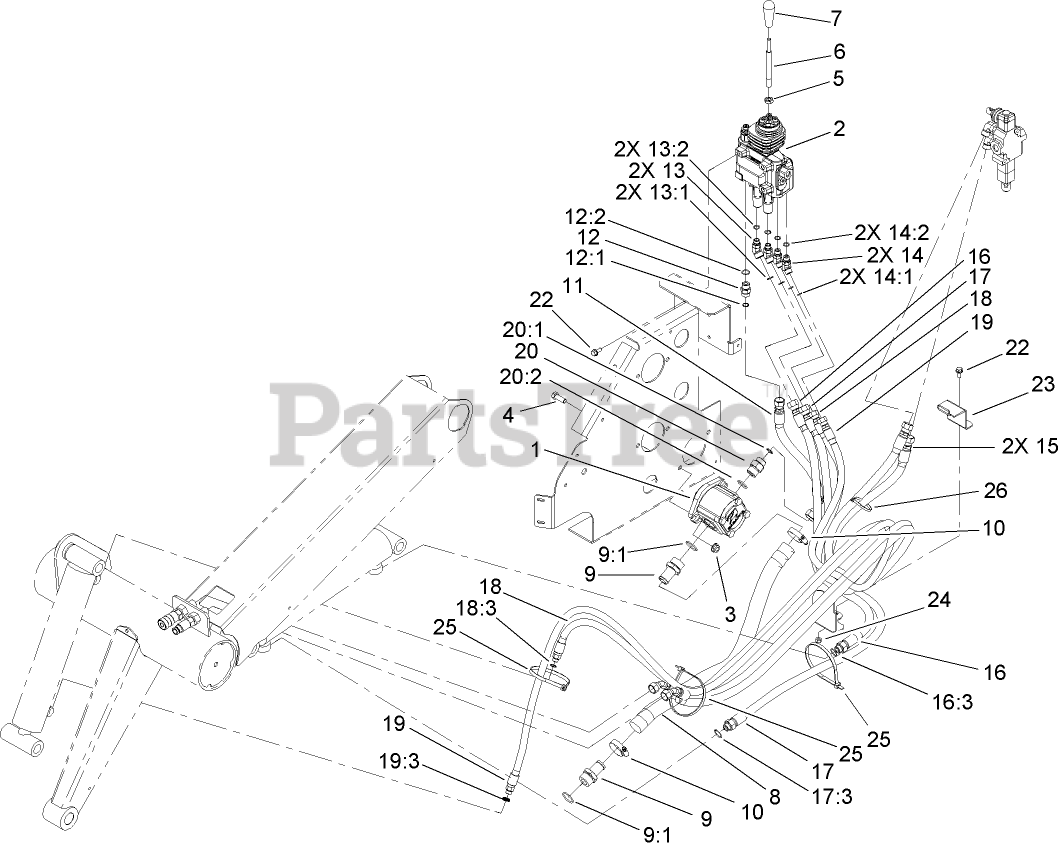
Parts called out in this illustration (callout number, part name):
1	PUMP-GEAR
1:1	KEY-SQUARE
1:2	SEAL KIT
2	VALVE-LOADER
3	NUT-HF
4	SCREW-HH
6	SHAFT-HANDLE, LIFT/TILT
7	KNOB-TAPERED
8	HOSE-HYD, SUCTION
9	FITTING-STR
9:1	O-RING
11	HYD HOSE ASM
12	FITTING-STRAIGHT
12:1	O-RING
12:2	O-RING
13	ADAPTER
13:1	O-RING
13:2	O-RING
14	FITTING-ELBOW-45
14:1	O-RING
14:2	O-RING
15	HYD HOSE ASM
16	HYD HOSE ASM
16:3	O-RING
17	HYDRAULIC HOSE ASM
17:3	O-RING
18	HYDRAULIC HOSE ASM
18:3	O-RING
19	HYDRAULIC HOSE ASM
19:3	O-RING
20	FITTING-STRAIGHT
20:1	O-RING
20:2	O-RING
22	SCREW-HHF
23	CLAMPHALF-HOSE
24	NUT-LOCK, NI
25	TIE-CABLE
26	TIE-CABLE
